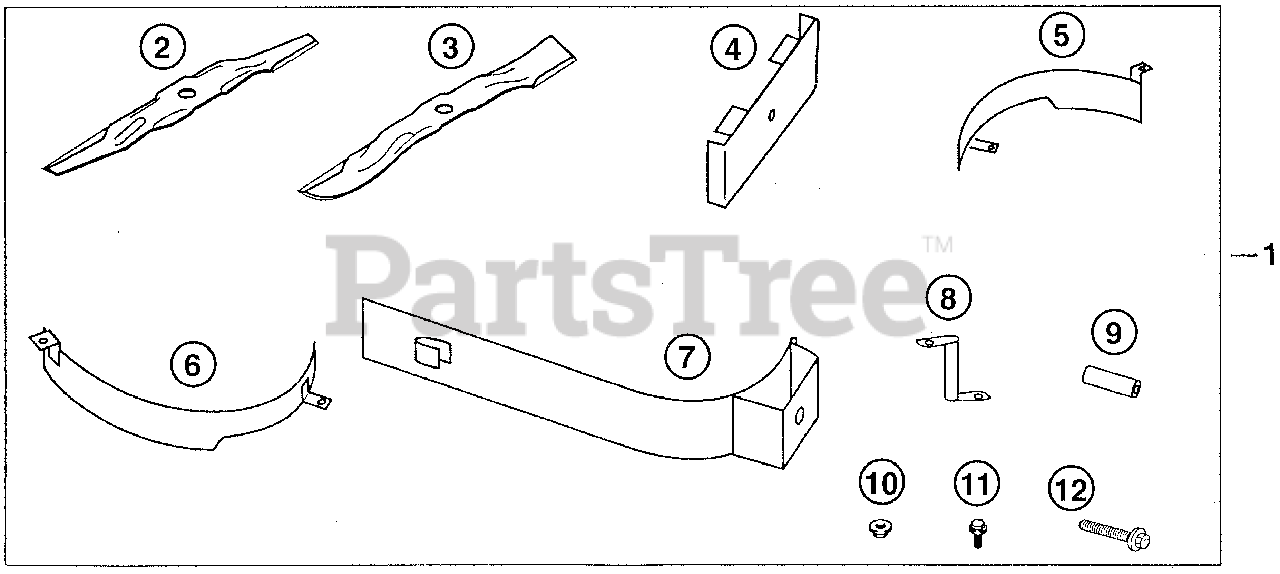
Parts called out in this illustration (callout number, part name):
1	MULCH KIT (42")
2	BLADE, LOW-LIFT
3	BLADE, ROTARY
4	PLATE, DISCHARGE
5	GUIDE A, SWIRL
6	GUIDE B, SWIRL
7	GUIDE C, SWIRL
8	ROD, SWIRL
9	SPACER, GUIDE
10	NUT, HEX. (8MM)
11	BOLT, FLANGE (8X15) (NOT AVAILABLE)
12	BOLT, FLANGE (10X60) (NOT AVAILABLE)
